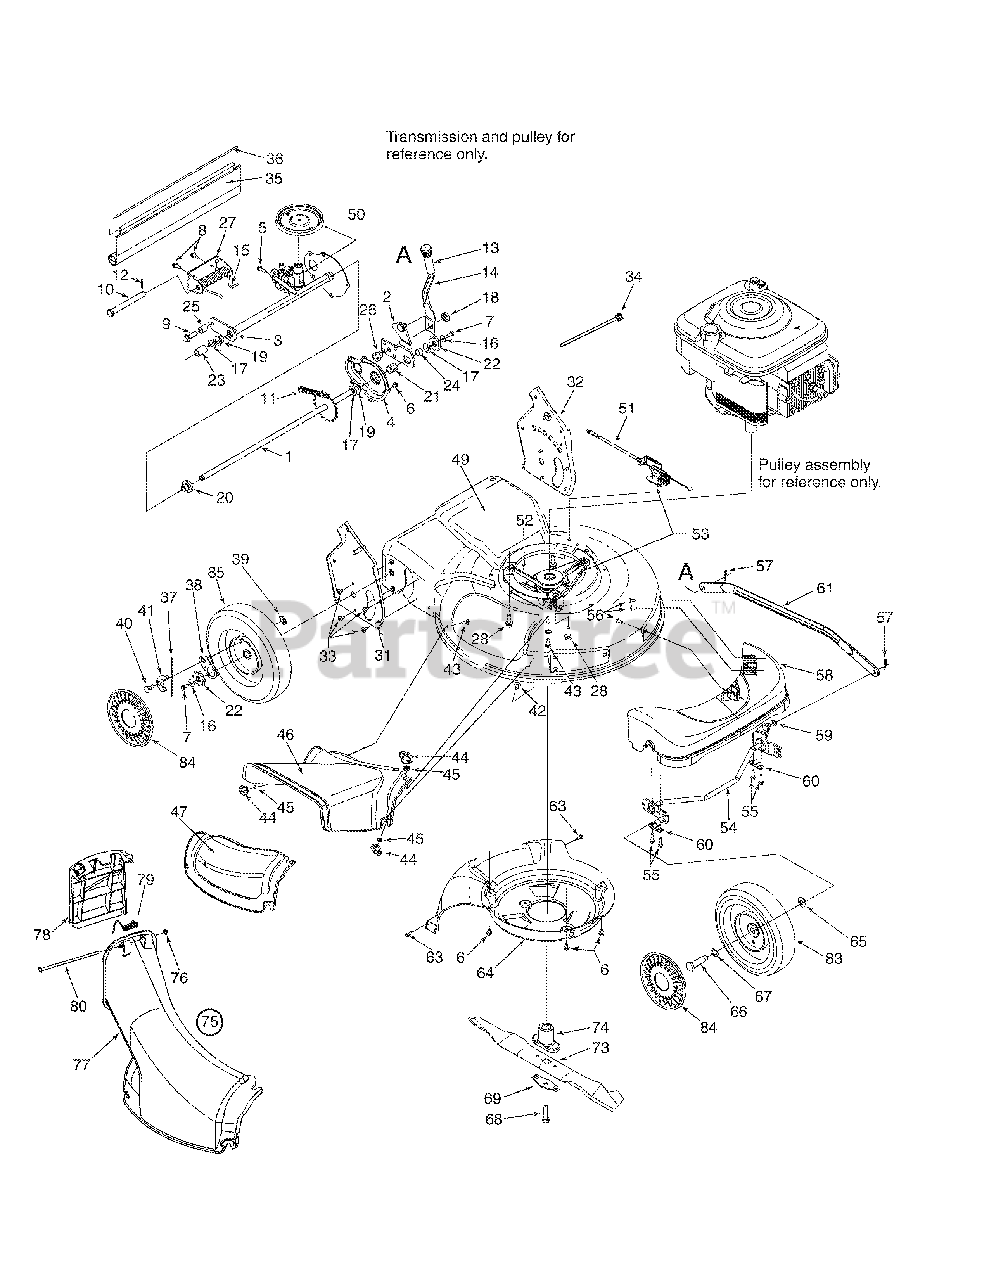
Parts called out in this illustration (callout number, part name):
1	Axle Ass’y 20T x 21.46" Lg.
2	Pivot Arm Ass’y
3	Trans Axle Ass’y
5	Hex Wash HD Scr 5/16-18 x .62
6	Hex Wash HD Tapp Scr 1/4-20 x .38
7	Hex Bolt 1/4-20 x .62
8	Hex Wash HD. TT Tap Scr. 1/4-20 x .62
9	TT Screw 3/8-16 x 1.25
10	Clevis Pin .5" Dia. x 4.62" Lg.
11	Chain, No. 48 End less .50 x 24 links
12	Cotter Pin
15	RH Torsion Sprocket
16	Cupped Wash. .25 ID x .88 OD x .062
17	Washer, Flat .505 ID x 1.0
18	Shoulder Nut .625 DIA. x .165
19	Flange Bearing .506 ID
20	Hex Flange Bearing
21	Hex Sleeve Bearing .504 x .830 Lg.
22	Ratchet Wheel
23	Spacer .55 ID x .75
24	Sleeve .511 id x .70 od x .37" lg.
25	Spacer .38 x .625" Lg.
26	Shoulder Spacer .385 ID x .715" Lg.
27	Spring Bracket
28	Hex Wash HD Tap Scr 3/8-16 x .88
29	Hex Wash Hd Screw 10-32 x 5/8
30	Clamp Casing - Throttle
31	Handle Brkt. Ass’y RH
32	Handle Brkt. Ass’y LH
33	Screw AB 1/4-20
35	Rear Flap 17.25" Lg.
36	Rear Flap Wire
37	Spring Nylon
38	Pawl Plate
39	Toplock Flat Weldnut 1/4-20
40	Shoulder Screw .340 x .285: 1/4-20
42	Carriage Bolt 1/4-20 x .62
43	Carriage Bolt 1/4-10 x .75
44	Wing Nut
45	Bolt Retainer 1/4" x .50" OD
47	Retainer Baffle
49	Deck Ass’y (w/o logo)
50	Transmission Ass’y
51	SP Cable 51.0" Lg.
52	V-Belt 3/8 x 39.24" Lg.
53	Pulley (6 speed Actuator)
55	Hex Wash. Hd. B-Tap Scr. 1/4 x 1.0"
56	Torx Hd. Scr. 5/16 x .75
57	Int. Cotter Pin 5/16 DIA
58	Front Cover- Grey
59	Bowed Washer
60	Bush ing Block .505 dia.
61	Single Lever Arm Control
63	Screw 1/4-15 X .75
64	Baffle
65	Cupped Wash .400 ID x .88 OD x .06
66	Axle Bolt
67	Wave Washer .51" ID
68	Hex Bolt 3/8-24 x 2.5" Lg.
69	Bell Blade Support
73	Blade 21" (Mulching)
74	Blade Adapter (w/star)
75	Chute Assembly
76	Push Cap .188 Rod
78	Chute Door
79	Torsion Spring
83	Front Wheel Ass'y 8 x 2.125 (Idle/Zag Ball Brg)
84	Hub Cap -Grey
85	Rear Wheel Ass’y 9 x 2.125 Drive/Zag/Blk)
86	Shroud - Yellow
